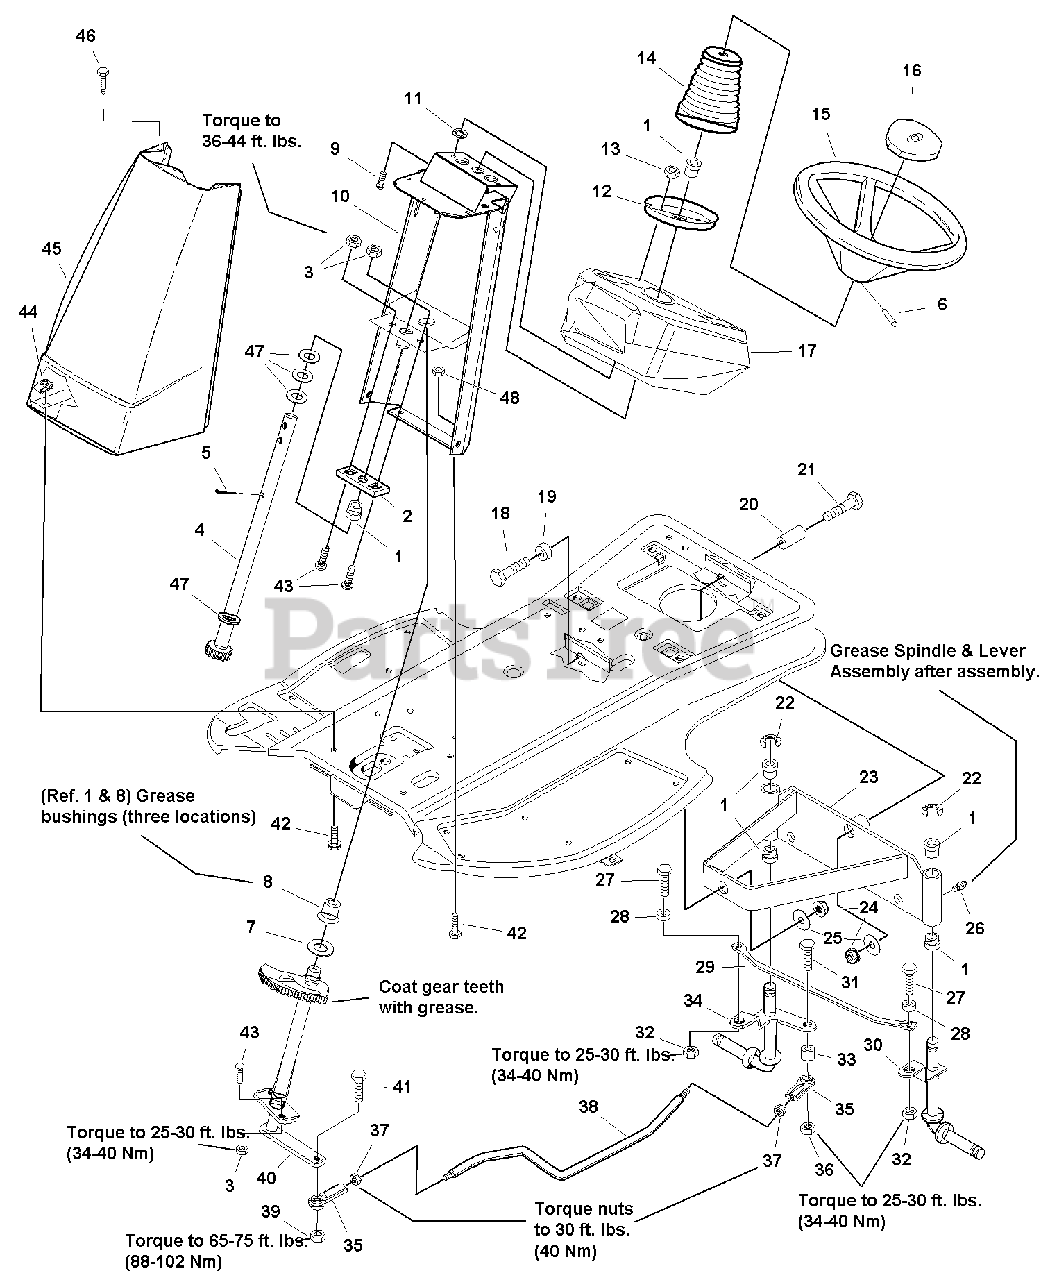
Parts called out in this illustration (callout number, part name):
1	BUSHING, Nylon
2	PLATE, Mounting
3	NUT, Hex Flange Whiz Lock, 3/8-16, Black
4	SHAFT & PINION ASSEMBLY
5	PIN, Cotter, Black
6	PIN, Spring, 5/16 x 2-1/2, Black
7	WASHER, 3/4
8	BUSHING, Metal
9	CARRIAGE BOLT, 1/4-20 x 3/4
10	SUPPORT ASSEMBLY
11	NUT, Push, 1/4, Black
12	PLATE, Mounting
13	NUT, Hex KEPS, 1/4-20, Black
14	COVER, Black Rubber
15	STEERING WHEEL
16	CAP, Steering Wheel, Simplicity
18	CAPSCREW, Hex Head, 1/2-13 x 1-3/4, Black
21	CAPSCREW, Hex Head, 1/2-13 x 3, Black
22	RING, Klip, External 3/4, Black
23	AXLE ASSEMBLY,w/Bushings & Lube Fitting
24	NUT, Hex Lock ESNA Heavy, 1/2-13, Black
25	WASHER, 1/2, Black
26	FITTING, Lube
27	CAPSCREW, Hex Head, 3/8-16 x 1, Black
28	SPACER, Powder Metal
30	SPINDLE & LEVER ASSEMBLY, RH (Lancer LH)
31	CAPSCREW, Hex Head, 3/8-16 1-1/2
32	NUT, Hex Flange Lock, 3/8-16, Black
34	SPINDLE & LEVER ASSEMBLY, LH (Lancer RH)
36	NUT, Hex Flange Lock, 3/8-16, Black
37	NUT, Hex Head, 1/2-20, Black
39	NUT, Hex Flange Two Way Lock, 1/2-13, Black
40	SHAFT & GEAR ASSEMBLY
41	CAPSCREW, Hex Head, 1/2-13 x 1-1/2, Black
42	CAPSCREW, Hex Head, 5/16-18 x 3/4
43	CARRIAGE BOLT, 3/8-16 x 1 , Black
44	NUT, Speed, 5/16-18
45	SHROUD, Steering (Orange)
45	SHROUD, Steering (Red)
46	CAPSCREW, Hex Head, 1/4-20 x 5/8, Black
47	WASHER, 3/4, Black
48	NUT, Hex Flange Lock, 5/16-18, Black
